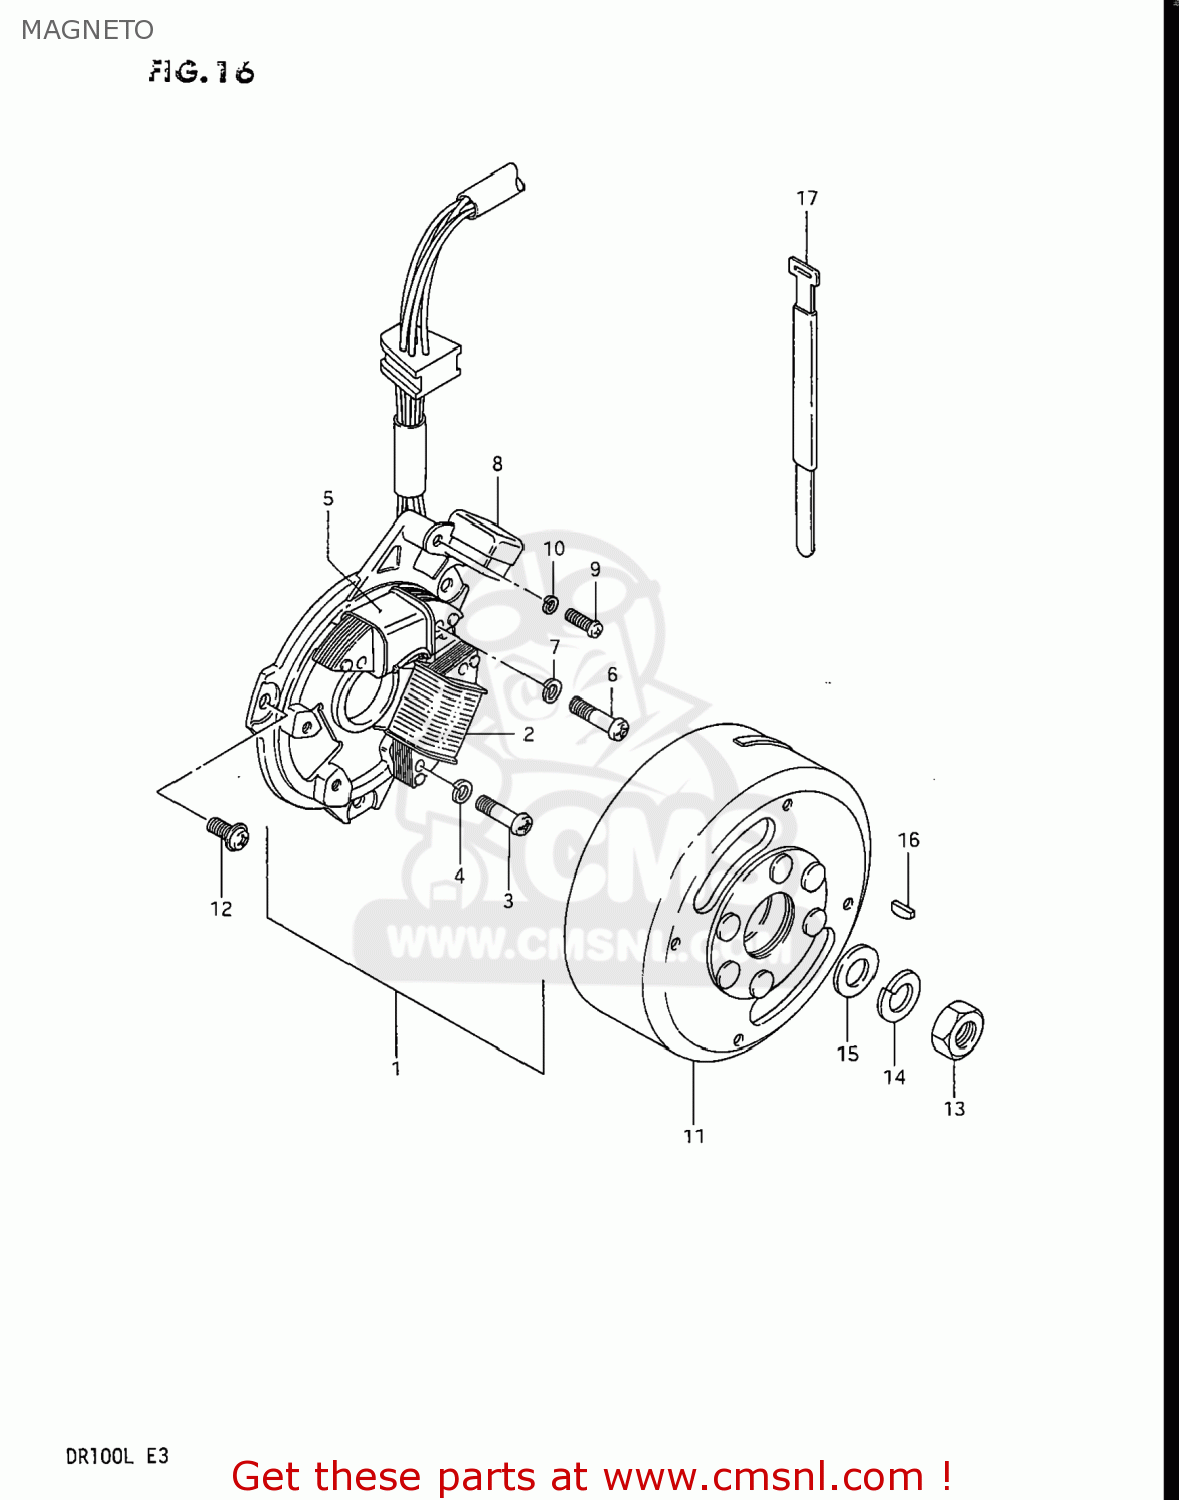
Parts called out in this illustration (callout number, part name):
1	STARTER ASSY
2	COIL,LIGHTING
3	SCREW
4	LOCK WASHER
5	COIL,IGNITION PRIMARY
6	SCREW
7	LOCK WASHER
8	COIL,PICK UP
9	SCREW
10	WASHER,LOCK 4M
11	ROTOR,FLYWHEEL
12	SCREW(5X14)
13	NUT (10MM)
14	WASHER,LOCK,10
15	WASHER
16	KEY
17	CLAMP L:110
